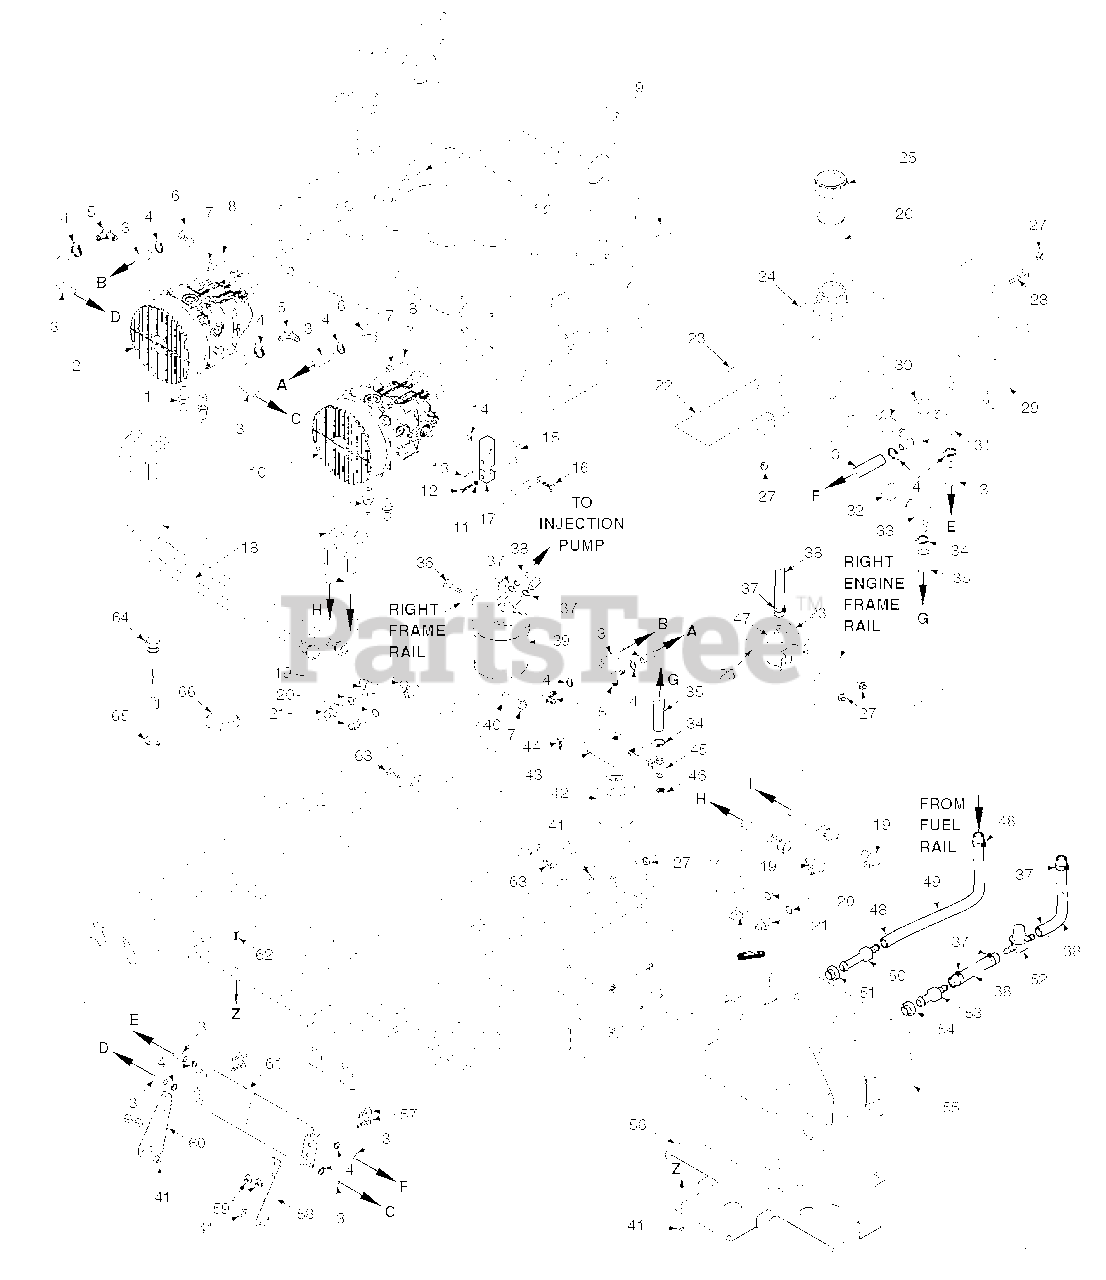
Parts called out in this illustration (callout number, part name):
1	Union, 3/4"-16 JIC x O-Ring
2	Pump, Right Hand, BDP 16A
3	Hose, 3/8" ID Pushlock
4	Hose Clamp, 0.69 dia.
5	Elbow, 90 Deg - 9/16 O-Ring x 3/8" Hose
6	Elbow, 90 Deg - 3/4 O-Ring x 3/8" Hose
7	Nut, Hex Elastic Stop 3/8-16
8	Flatwasher, 3/8" (.391 x .938 x .105) Grade 8
9	Bolt, Hex Head 3/8-16 x 1.5"
10	Pump, Left Hand, BDP-16A
11	Lockwasher, 1/4" Spring
12	Bolt, Hex Head, 1/4-20 x 1-1/2"
13	Roll Pin, Spring 3/16 x 3/4"
14	Nut, Center Lock 3/8-16
15	Clamp Plate, Pump Control
16	Bolt, Hex Head, 3/8-16 x 1-3/4"
17	Block, Pump Control
18	Hose Assembly, Pump
19	Elbow, 90 Degree, 7/8-14 THD
20	O-Ring
21	Bushing, 7/8-14 JIC x 3/4-16 O-Ring
22	Strap, Hydraulic Tank
23	Bolt, Hex Head 1/4-20 x 3/4"
24	Oil Reservoir Assembly
25	Cap, Hydraulic Tank
26	Insert, Filler Neck
27	Nut, Hex Elastic Stop 1/4-20
28	Screw, Phillips Head, 1/4-20
29	Support Bracket, Hydraulic Tank
30	Bushing, .56 Dia. Viton
31	Elbow, 90 Degree .38 Hose
32	Bushing, .78 Dia. Viton
33	Elbow, 90 Degree
34	Clamp, Hose
35	Hose Assembly, 1/2" ID
36	Bolt, Carraige 3/8-16 x 1"
37	Clamp, Fuel Hose 5/16" ID
38	Fuel Hose, 5/16" ID. Non-Perm
39	Fuel Filter
40	Flatwasher, 3/8" (.391 x .938 x .105)
41	Nut, Serrated Flange 5/16-18
42	Oil Filter
43	Oil Filter Base
44	Bolt, Hex Head 5/16-18 x1.0" Zinc
45	Tee, 3/4 O-Ring x JIC x 1/2" Hose
47	Fuel Pump, Cat
48	Clamp, 3/16" ID
49	Hose, 3/16" Fuel Line
50	Hose Fitting
51	Bushing
52	Valve, Fuel Shutoff
53	Fitting, Hose with Screen
54	Bushing
55	Fuel Tank Assembly
56	Support Bracket, Fuel Tank
57	Bolt, Carraige 1/4-20 x 3/4"
58	Mounting Bracket - LH, Oil Cooler
59	Nut, Serrated Flange 1/4-20
60	Mounting Bracket - RH, Oil Cooler
61	Oil Cooler
62	Bolt, Carraige 5/16-18 x 3/4"
63	Bolt, Hex Head 5/16-18 x 3/4"
64	Fuel Gauge Assy.
65	Seal, Fuel Gauge
66	Cap, Fuel Tank
